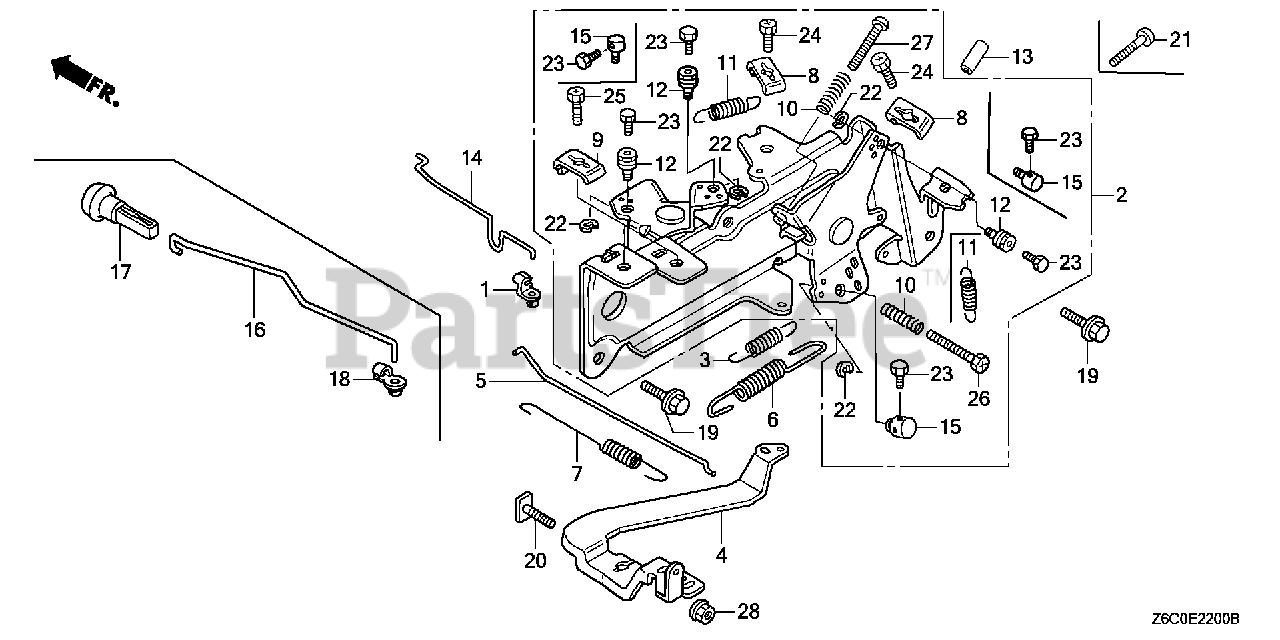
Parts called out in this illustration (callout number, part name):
1	JOINT, ROD
2	CONTROL ASSY.
3	SPRING, STARTER
4	ARM, GOVERNOR
5	ROD, GOVERNOR
6	SPRING, GOVERNOR
7	SPRING, THROTTLE RETURN
9	HOLDER, CABLE
10	SPRING, CONTROL ADJUSTING
11	SPRING, CABLE RETURN
14	ROD, CHOKE CONTROL
19	BOLT, FLANGE (6X14) (CT200)
20	BOLT, GOVERNOR ARM
25	BOLT, RECESSED (5X16)
26	BOLT, RECESSED (5X25)
27	SCREW, PAN (5X25)
28	NUT, FLANGE (6MM)
